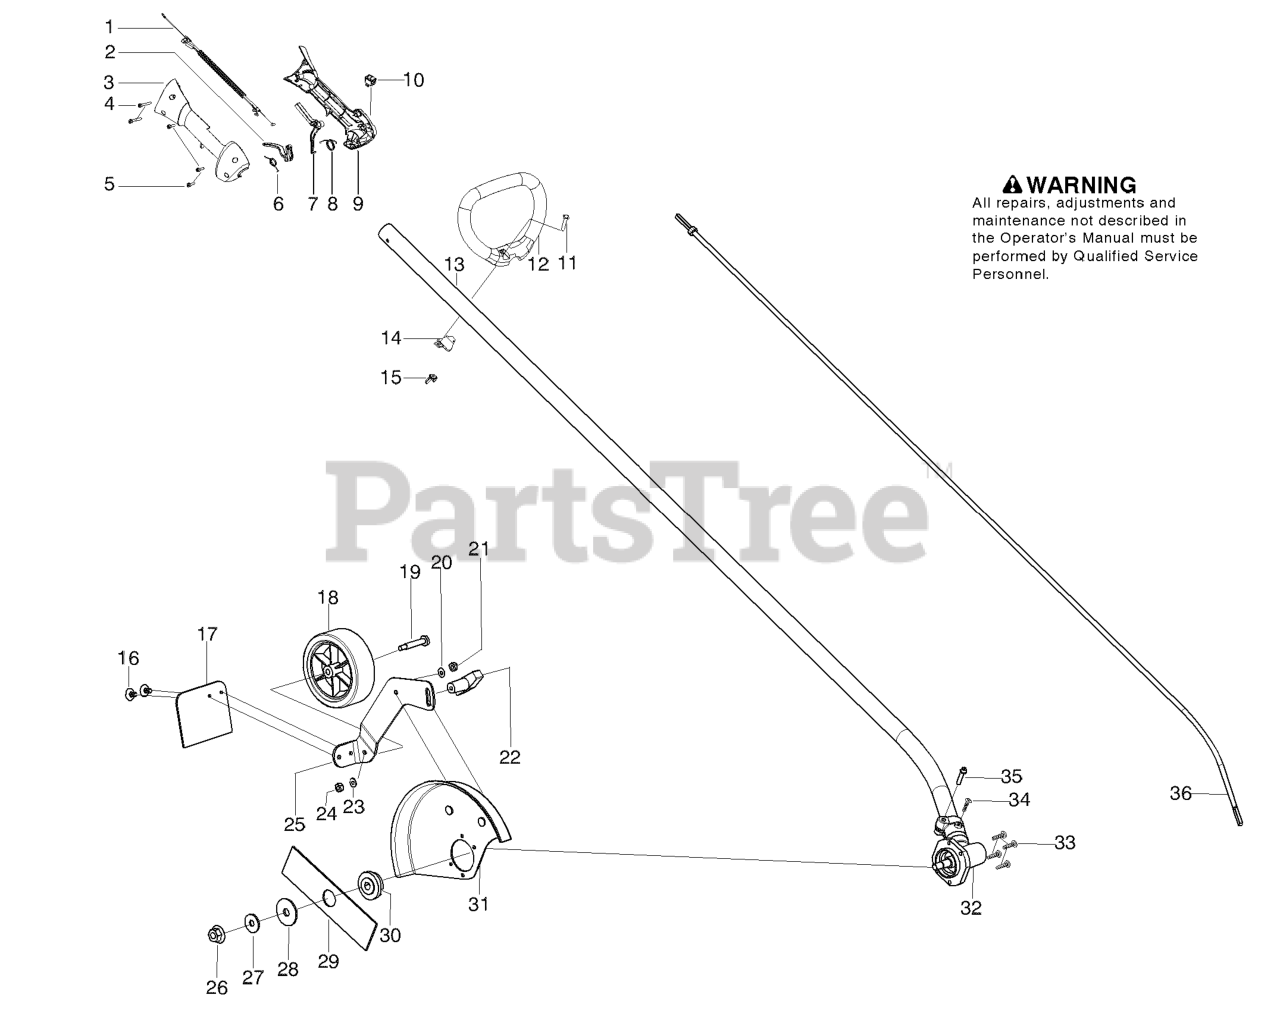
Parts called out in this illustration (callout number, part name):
1	Assy-Cable/Wire Harness
2	TRIGGER THROTTLE
3	HOUSING-THROTTLE RH
5	SCREW M4 X 1.75 PT 16MM
6	SPRING TRIGGER
7	THROTTLE LOCKOUT
8	SPRING LOCKOUT
9	HSG THROTTLE LH
10	KIT SWITCH
11	BOLT, TYPE 2
13	KIT-DRIVESHAFT
14	CLAMP ASSIST HANDLE
15	WINGNUT, TYPE 2
16	FASTENER MUD FLAP
17	KIT MUD FLAP
18	WHEEL-4"(FRONT)(RUBBER)
19	BOLT-SHOULDER AXLE
25	WHEEL BRKT ADJ
26	NUT-FLANGE (LH)
27	WASHER BELLVILLE
28	WASHER-FLAT.
31	KIT - EDGER GUARD
32	KIT GEARBOX EDGER HUSQ
33	SCR 10-24 MS LDK PAN PH
34	SCREW 8-16 X 9/16 (PLAS
35	SCREW - CARB. ADAPTOR
36	Flexshaft
